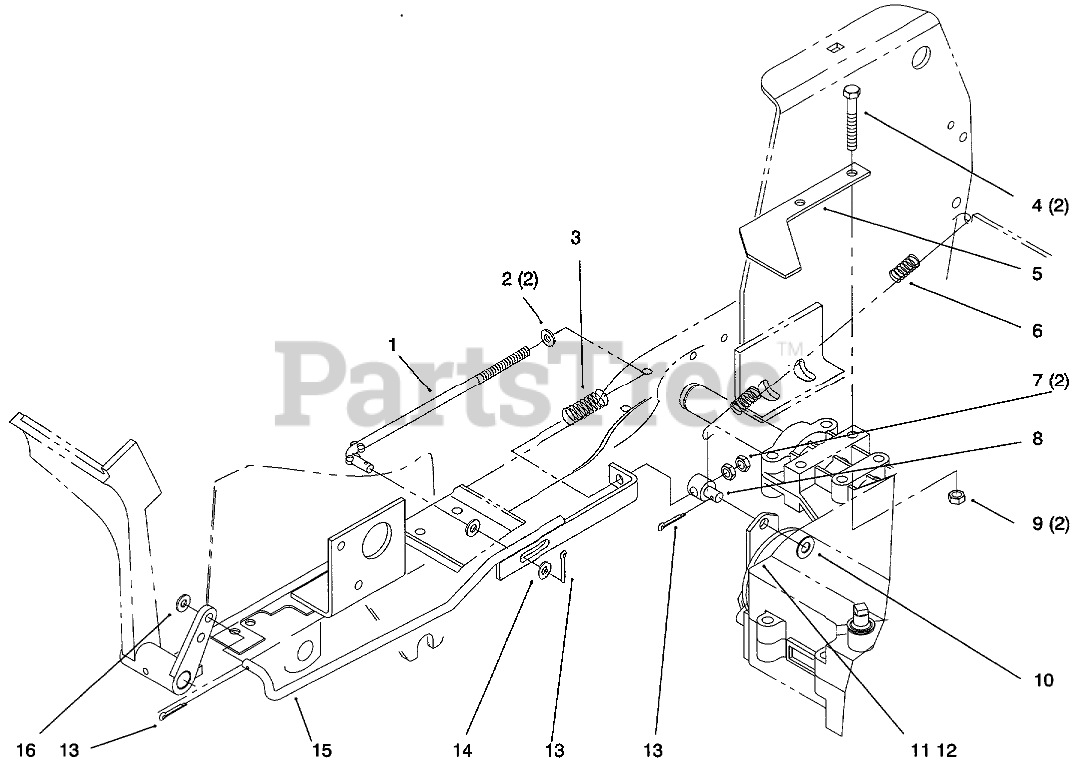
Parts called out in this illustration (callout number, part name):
1	ROD - SPRING
2	WASHER-PLAIN
3	SPRING - COMPRESSION
4	SCREW-HH
5	STOP - BRAKE
6	SPRING - EXTENSION
7	NUT-JAM
8	TRUNION
9	NUT-LOCK, NI
10	WASHER-FLAT
11	Pad-Brake 2/Pkg
13	PIN-COTTER
14	WASHER-PLAIN
15	Brake Arm
16	WASHER-FLAT
